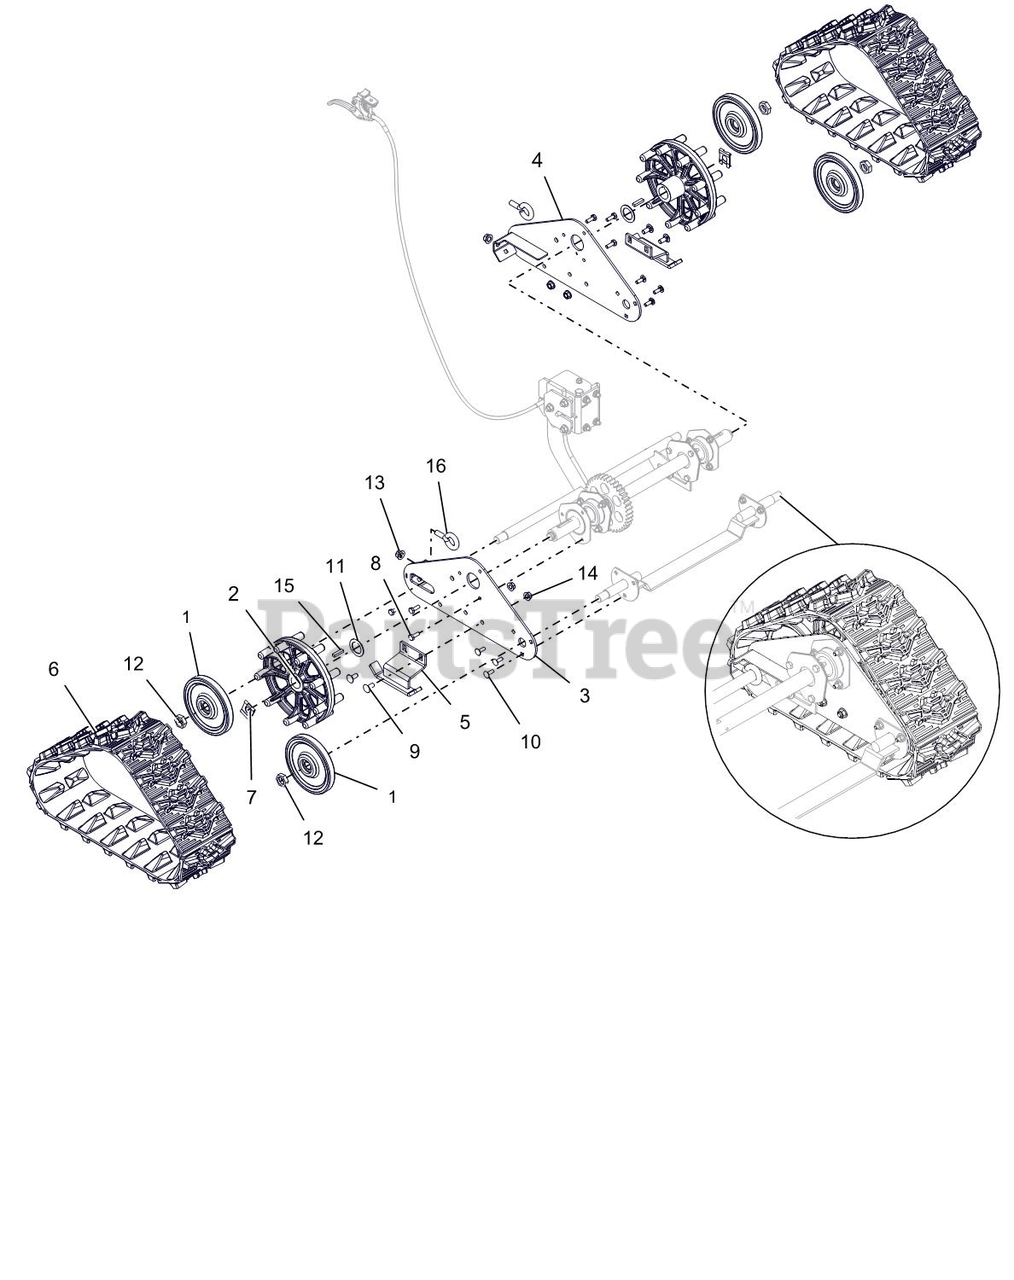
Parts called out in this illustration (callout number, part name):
1	WHEEL, BOGIE - SINGLE BEARING
2	WHEEL, MACHINED DRIVE
3	SIDE PLATE, RH COMPACT BLACK
4	SIDE PLATE, LH-COMPACT TRACK B
5	RUNNER, GUIDE-CMPT TRACK BLACK
6	TRACK, RUBBER COMPACT
7	CLIP, SNAP .625 DIA
8	@BLT-HEX .25-20X.75 GR5 YWZC
9	@BLT-RDHDSQNK .31-18X.75 G5YZ
10	@BLT-RDHDSQNK .25-20X.75 G5YZ
11	WSHR-FL-STL 1.010X1.505X.062YZ
12	@NUT-LK-NYL .625-18 YWZC
13	NUT-LK-CTR-FLG .38-16 YWZC
14	@NUT-LK-TOP-FLG .31-18 YWZC
15	KEY-RECT .25X.188X1.00
16	BLT-EYE .375-16X.880 YWZC
